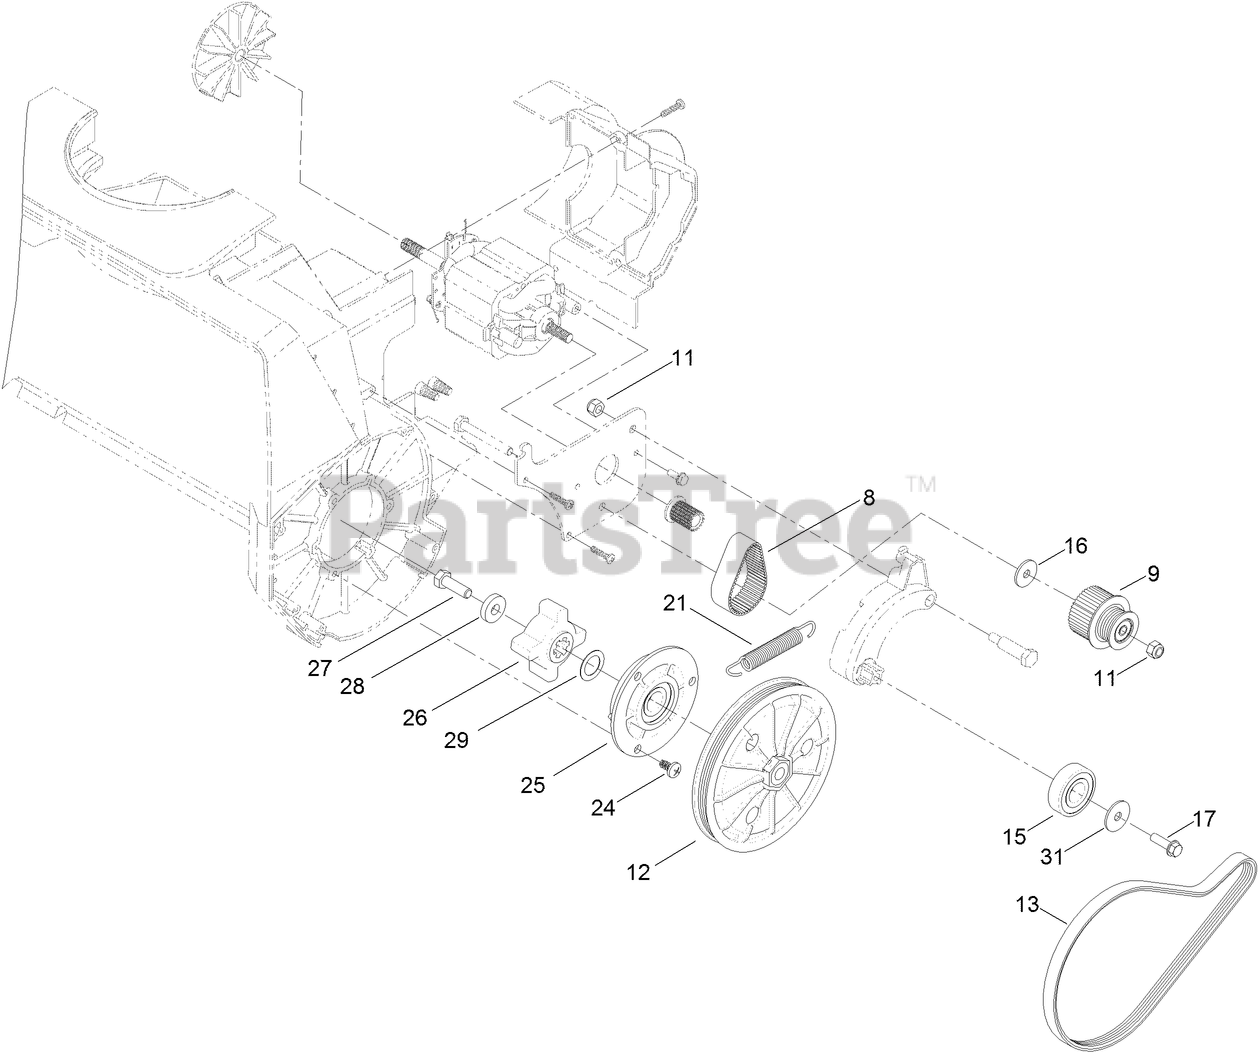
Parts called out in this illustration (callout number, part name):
8	BELT-PULLEY, IDLER/DRIVER
9	IDLER PULLEY ASM
11	NUT-LOCK, NI
12	PULLEY ASM
13	BELT-DRIVE
17	SCREW-HWH
21	SPRING-IDLER
24	SCREW-SEAT, SWITCH
25	PILLOW BLOCK ASM
26	COUPLER-PULLEY
29	WASHER-PLAIN
31	WASHER-FLAT
